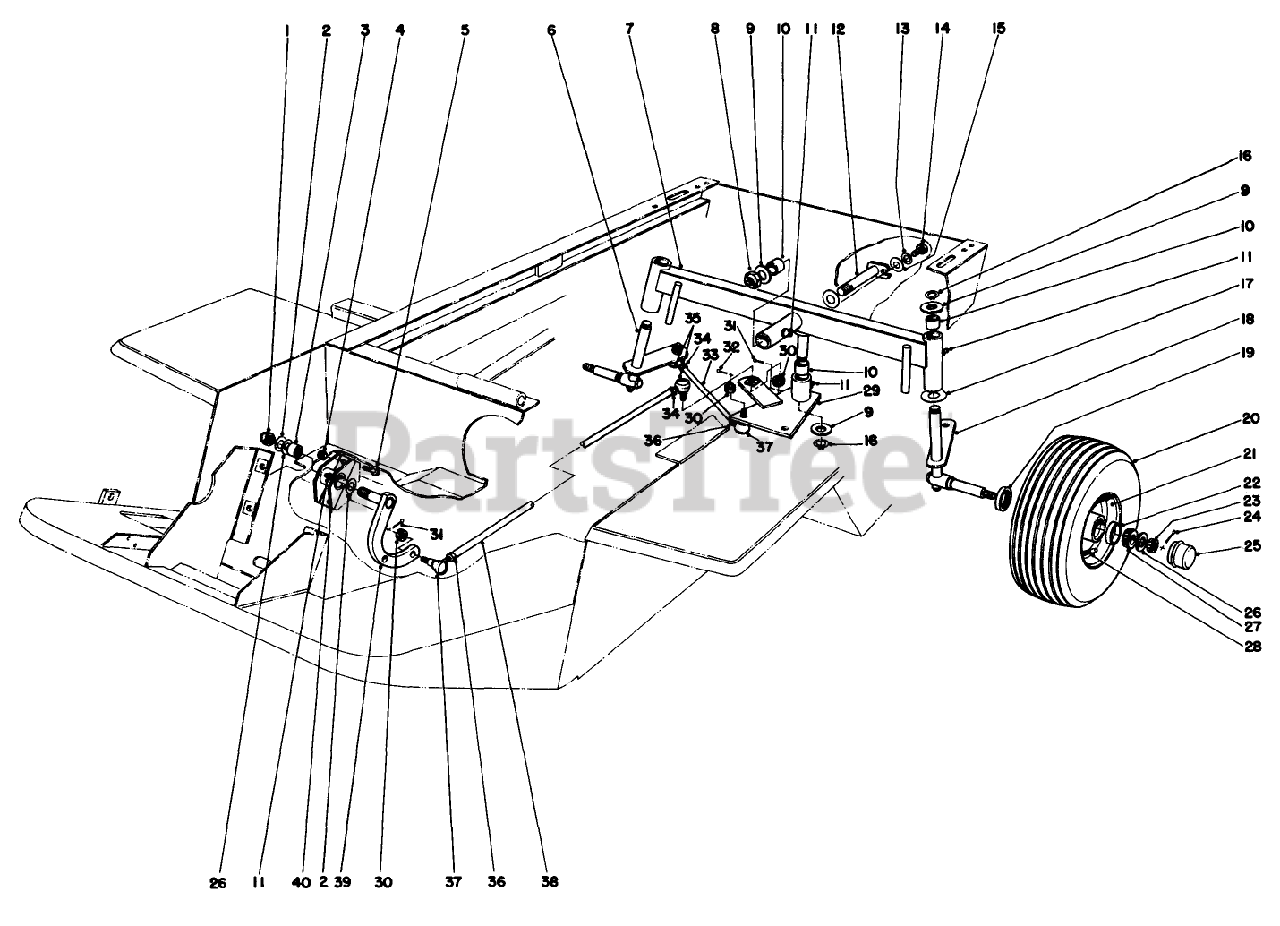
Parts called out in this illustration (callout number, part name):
1	NUT-LOCK, NI
2	THRUST WASHER
3	BEARING-NEEDLE
4	NUT-LOCK, NI
5	SCREW-HH
6	Spindle R.H.
7	Rear Axle (Incl. Ref. #10 & 11)
8	NUT-LOCK, NI
9	WASHER-THRUST
10	BUSHING
11	FITTING-GREASE
12	Pin-RearAxle
13	WASHER-LOCK
14	SCREW-HH
15	WASHER-FLAT
16	RING-RETAINING
17	WASHER-THRUST
18	Spindle L.H.
20	TIRE 4 PLY
21	Rim (Incl. Ref. #22)
22	BEARING-CUP, TAPERED
23	NUT-HEX, SLOTTED
24	PIN-COTTER
25	CAP-DUST
26	WASHER-FLAT
27	BEARING-CONE, TAPERED
28	VALVE STEM AND CAP ASM
29	Steering Plate (Incl. Ref. #10 & 11)
30	NUT-SLOTTED
31	PIN-COTTER
32	PIN-COTTER
33	STRG TIE ROD R
34	NUT-HJ (LH THREAD)
35	Socket Assembly L.H. (Incl. Ref. #30)
36	NUT-JAM
37	Socket Assembly R.H. (Incl. Ref. #30)
38	REAR STRG TUBE PP
39	PIVOT ARM WA
40	Pivot Mount (Incl. Ref. #3 & 11)
